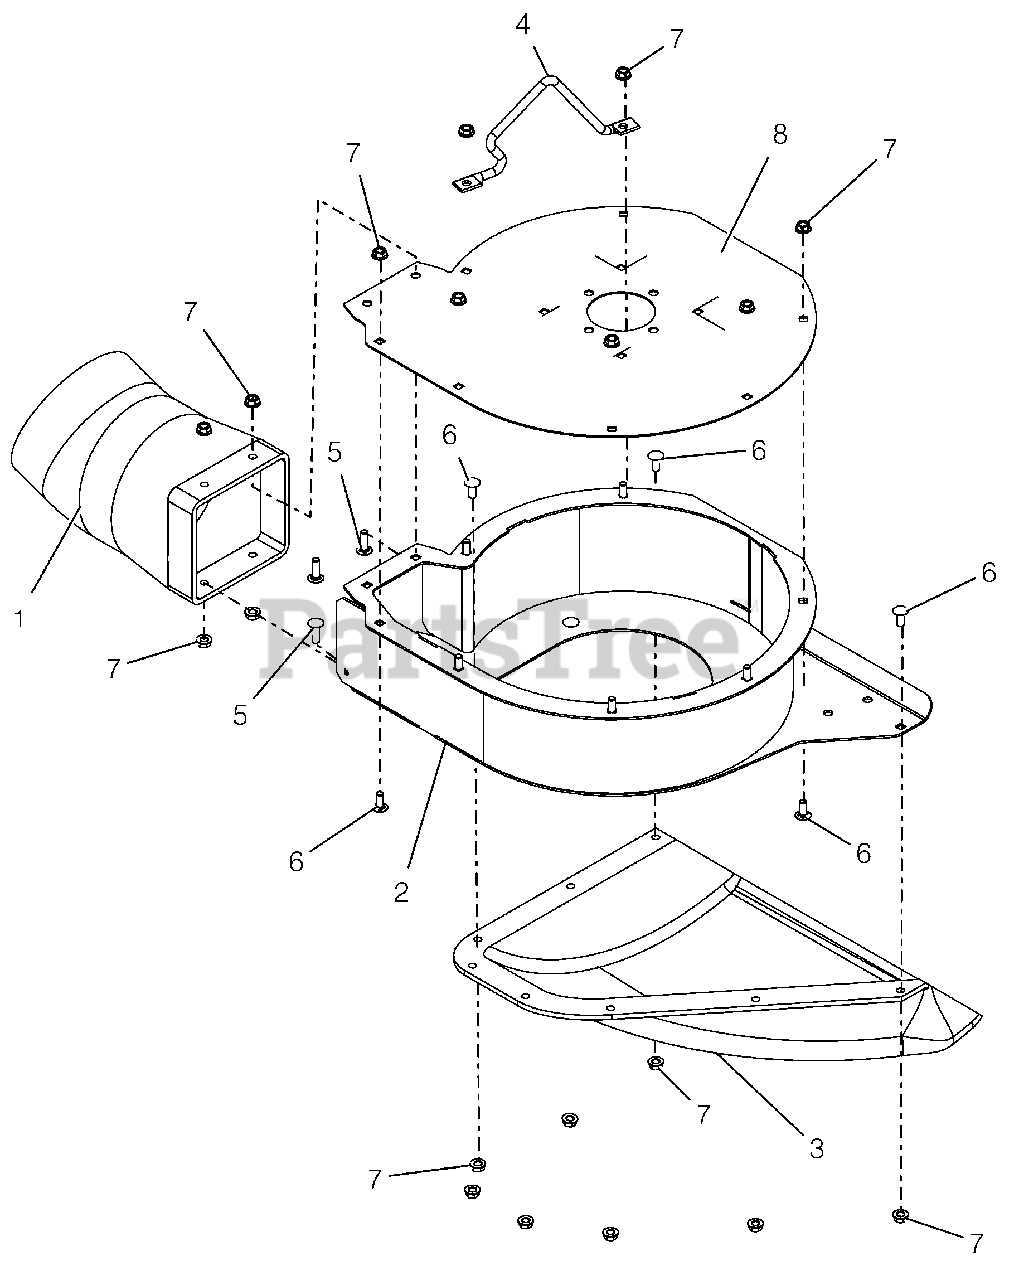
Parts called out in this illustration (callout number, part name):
1	ADAPTER, HOSE
2	WLDMT, HOUSING SCROLL (BLACK)
3	PLENUM, GRASS PUMP
4	HANDLE, BOLT-ON
5	@BLT-RHDSSQNK .31-18X1.00 G5YZ
6	@BLT-RHDSSQNK .31-18X.75 G5YZ
7	@NUT-LK-TOP-FLG .31-18 YWZC
8	PLT, BLOWER COVER (BLACK)
